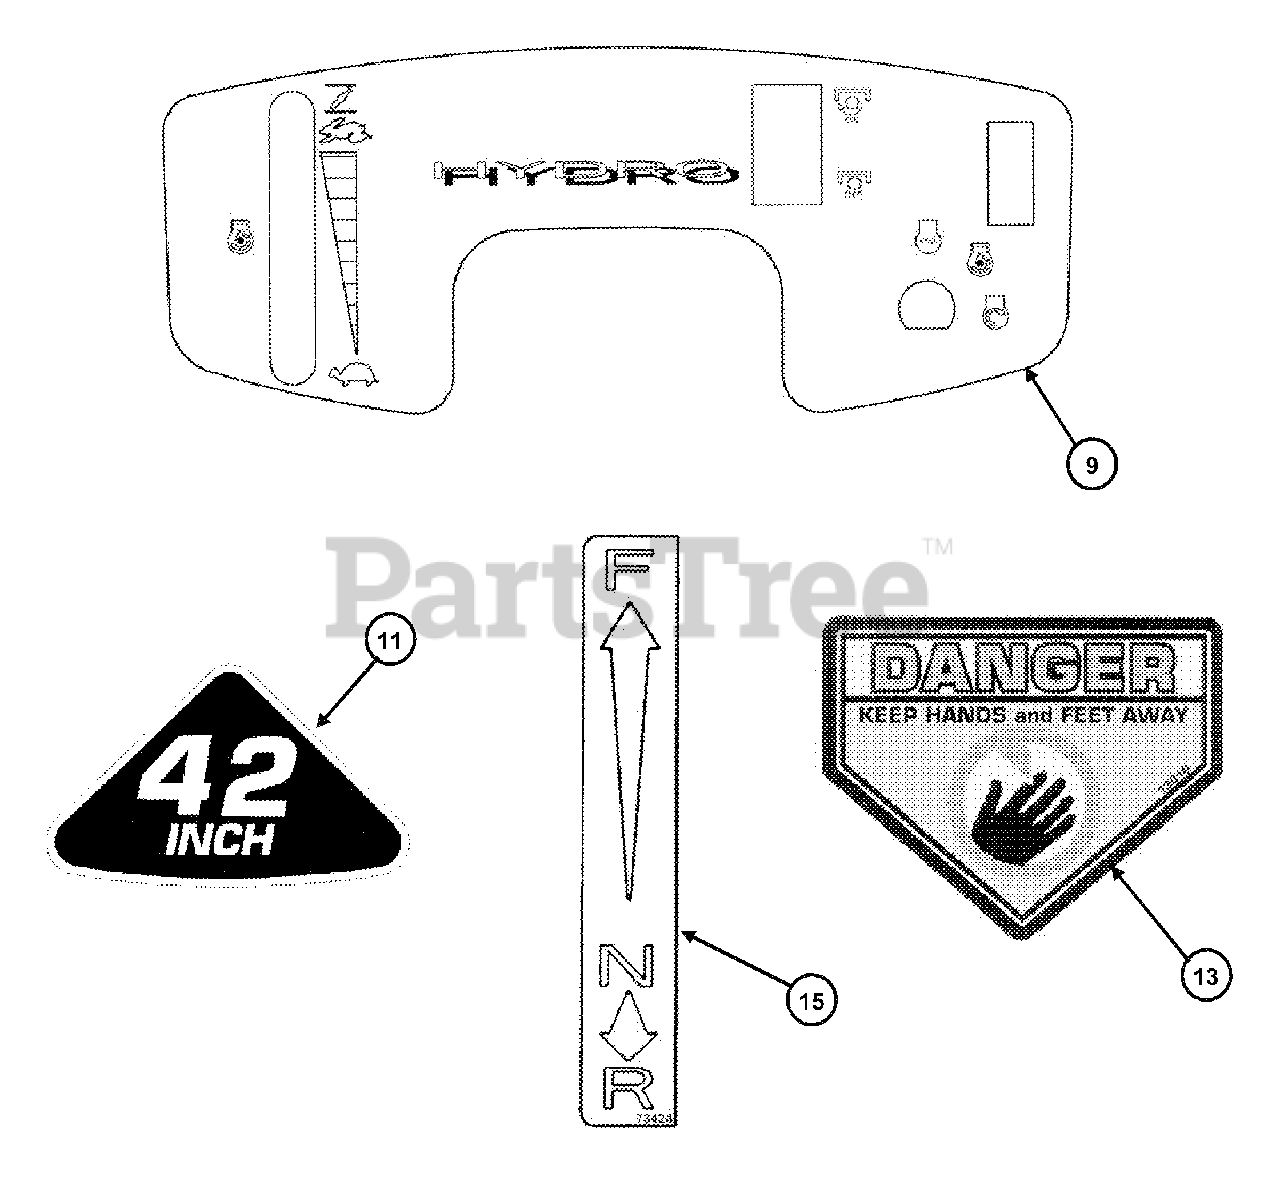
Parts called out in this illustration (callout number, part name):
9	DECAL, Console w/Headlights (All except LT180H48GBV2)
9	DECAL, Console w/Indicator Lights (LT180H48GBV2 Only)
11	DECAL, 42" Deck
13	DECAL, Danger CPSC
15	DECAL, Shift Cover
